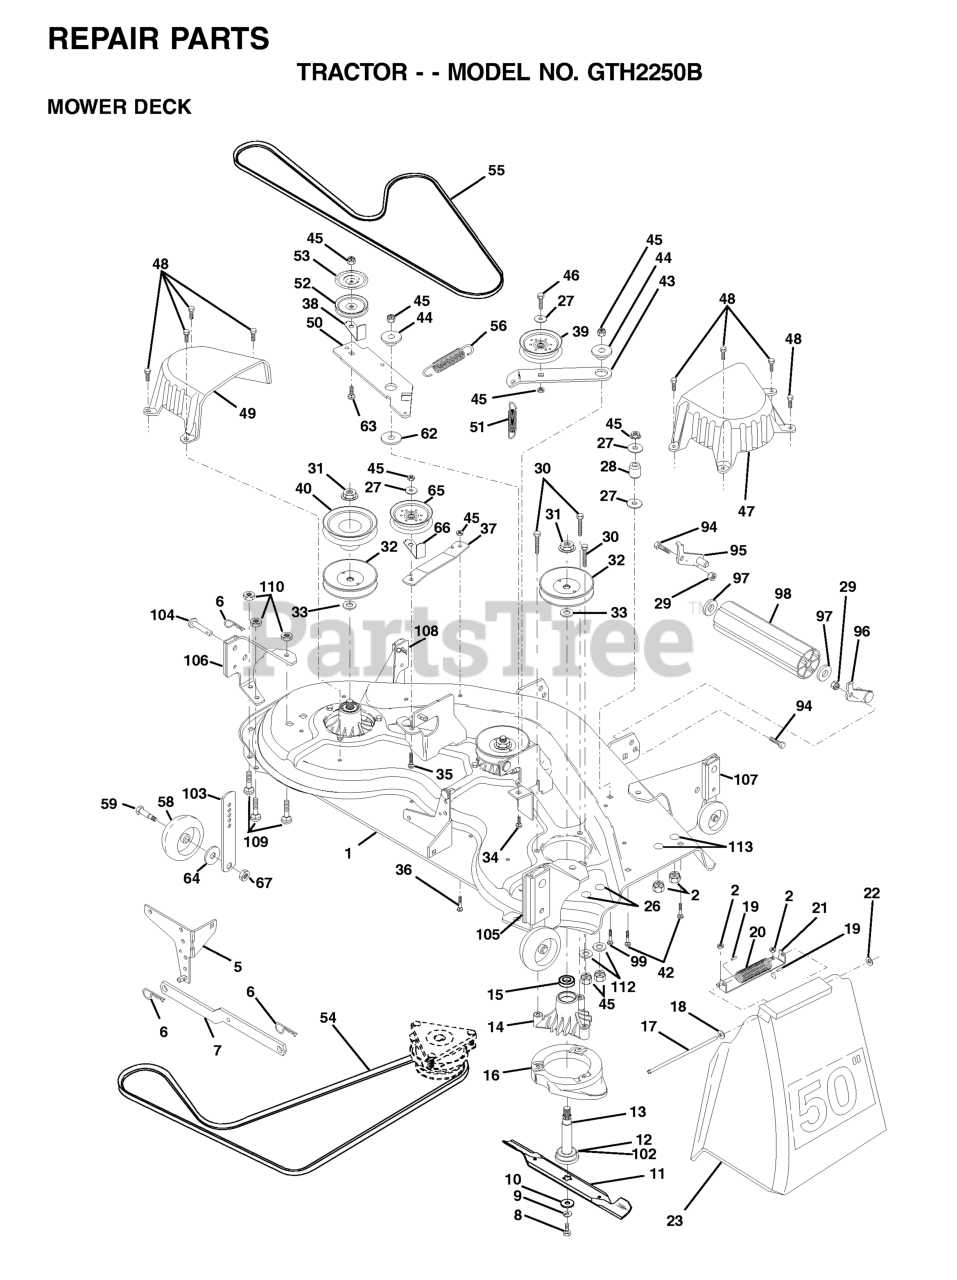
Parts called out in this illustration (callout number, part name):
2	LOCKNUT
5	BRACKET SWAY BAR
6	RETAINER-SPRNG RB
7	REAR SUSP ARM
8	BLADE BOLT
9	LOCKWASHER
10	WASHER.BLADE
11	BLADE.50".HI-LIFT
13	SHAFT.ASM.W/BEARING
14	HOUSING.MANDREL.44/46" VENT
16	STRIPPER.MANDREL.ROUND.BLACK
17	ROD-HINGE T
18	Washer 11/32 x 5/8 x 16 Ga SD
19	CAP-SLEEVE LT
20	SPRING TORSION
21	BRACKET, DEFLECTOR
22	NUT PUSH M
27	WASHER
28	IDLER SPRING SPACER
29	NUT.71038.31-18.HEX.NYLOCK
30	SCREW THDROL ROLLING WASHER HD
31	NUT
32	PULLEY MANDREL
33	WASHER
34	BOLT.3/8-14X1.25
36	BOLT D
37	STIFFENER ARM
38	KEEPER.BELT.IDLER.PLATED
39	PULLEY.IDLER.FLAT
42	RP BOLT 5/16-18 X3/4 ZN/YEL GR
43	ARM.IDLER.SEC.44"
44	SPACER RETAINER
46	BOLT
47	COVER MANDRELL
48	SCREW.1/4-20X5/8
49	COVER.MANDREL.LH.44"
50	ARM.IDLER.PRIMARY
51	SPRING.SEC.44"VEN
52	PULLEY IDLER
53	SHIELD IDLER
54	V-BELT.PRMRY 46/50 VENT.BLK BK
55	BELT V SECONDARY
58	WHEEL GAGE DONUT
59	BOLT, SHOULDER
62	HARDENED WASHER
63	BOLT.3/8-16X1.50
64	WASHER.5/16.FLAT.STE.STD.
66	KEEPER BELT IDLER PLATED
67	LOCKNUT
94	BOLT.FIN.HEX.5/16-18UNC X 1.00
95	BRACKET ASM, ROLLER (L)
96	BRACKET ASM, ROLLER
97	Washer 1 17/32 X 7/8 X 16 Ga
98	NOSE ROLLER
103	BAR.ADJUST.WHEEL.ANTI.SCALP.BL
104	RIVET.PIN.HEAD.YELLOW.
112	WASHER
113	BOLT.CARR.5/16-18X1/2
